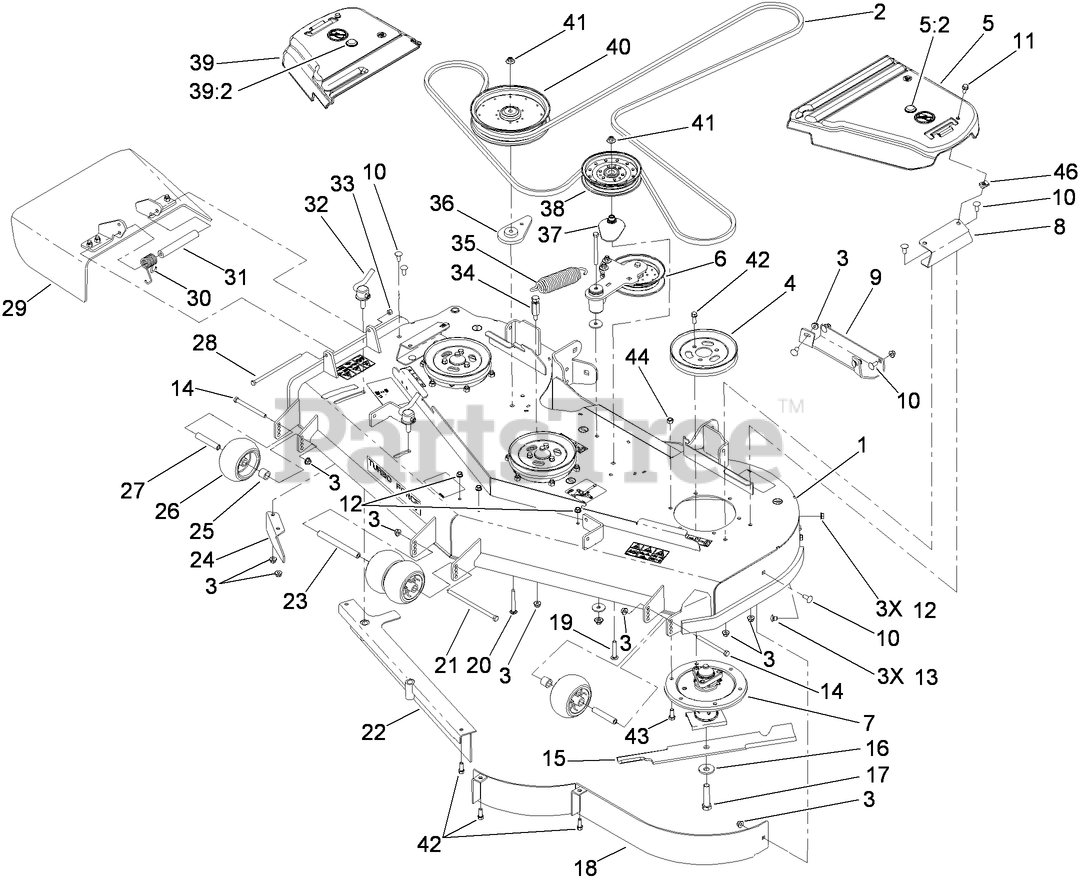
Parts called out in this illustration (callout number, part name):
1	DECK DECAL ASM
2	BELT-V
3	NUT-HF, NI
4	Pulley
5	LH BELT COVER ASM
5:2	PLUG-PLASTIC
6	IDLER ARM ASM
7	SPINDLE ASM
8	BRACKET-COVER, BELT
9	Plate-Skid
10	SCREW-CARR
11	SCREW-HHF
12	NUT-HHF, WHIZ
13	SCREW-CARR
14	SCREW-HH
15	BLADE-HI FLOW
16	Washer-Blade Bolt, Heavy
17	Screw-Cap
19	BOLT-CARR, SHORT NECK
20	SCREW-CARR
21	SCREW-HH
23	SPACER-WHEEL
24	BAFFLE-DISCHARGE
25	TUBE-SPACER
26	ROLLER-SCALP, ANTI
27	TUBE-SPANNER
28	SCREW-HH
29	RUBBER DEFLECTOR ASM
30	SPRING-TORSION
31	SPACER
32	LEVER ASM
33	NUT-LOCK, NI
34	ANCHOR-SPRING, TALL
35	EXTENSION-SPRING
36	SPACER-IDLER
37	SPACER-PULLEY
38	PULLEY-IDLER, FLAT
39	RH BELT COVER ASM
39:2	PLUG-PLASTIC
40	PULLEY-IDLER
41	NUT-FLANGE, NI
42	SCREW-HWH
43	SCREW-HH
44	NUT-LOCK, NI
46	NUT-U
